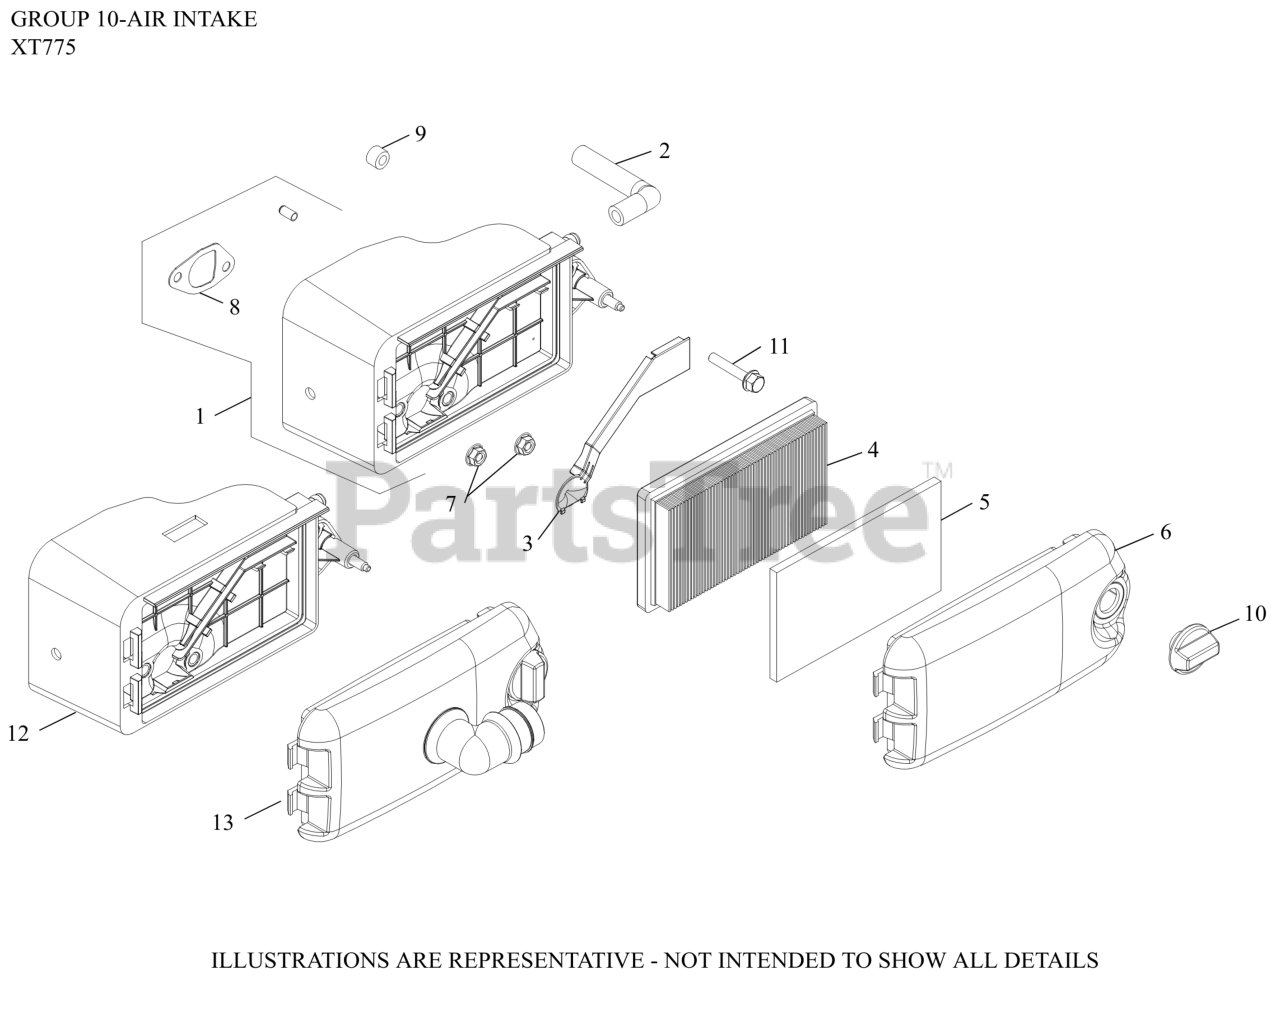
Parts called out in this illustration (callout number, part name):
1	KIT, AIR CLEANER BASE
3	COVER, A/C BASE (BREATHER GAS)
4	ELEMENT, AIR FILTER
5	ELEMENT, PRE-CLEANER
6	COVER, AIR CLEANER
10	KNOB-USE 14 341 07-S
11	SCREW, HEX FLANGE (M6)
